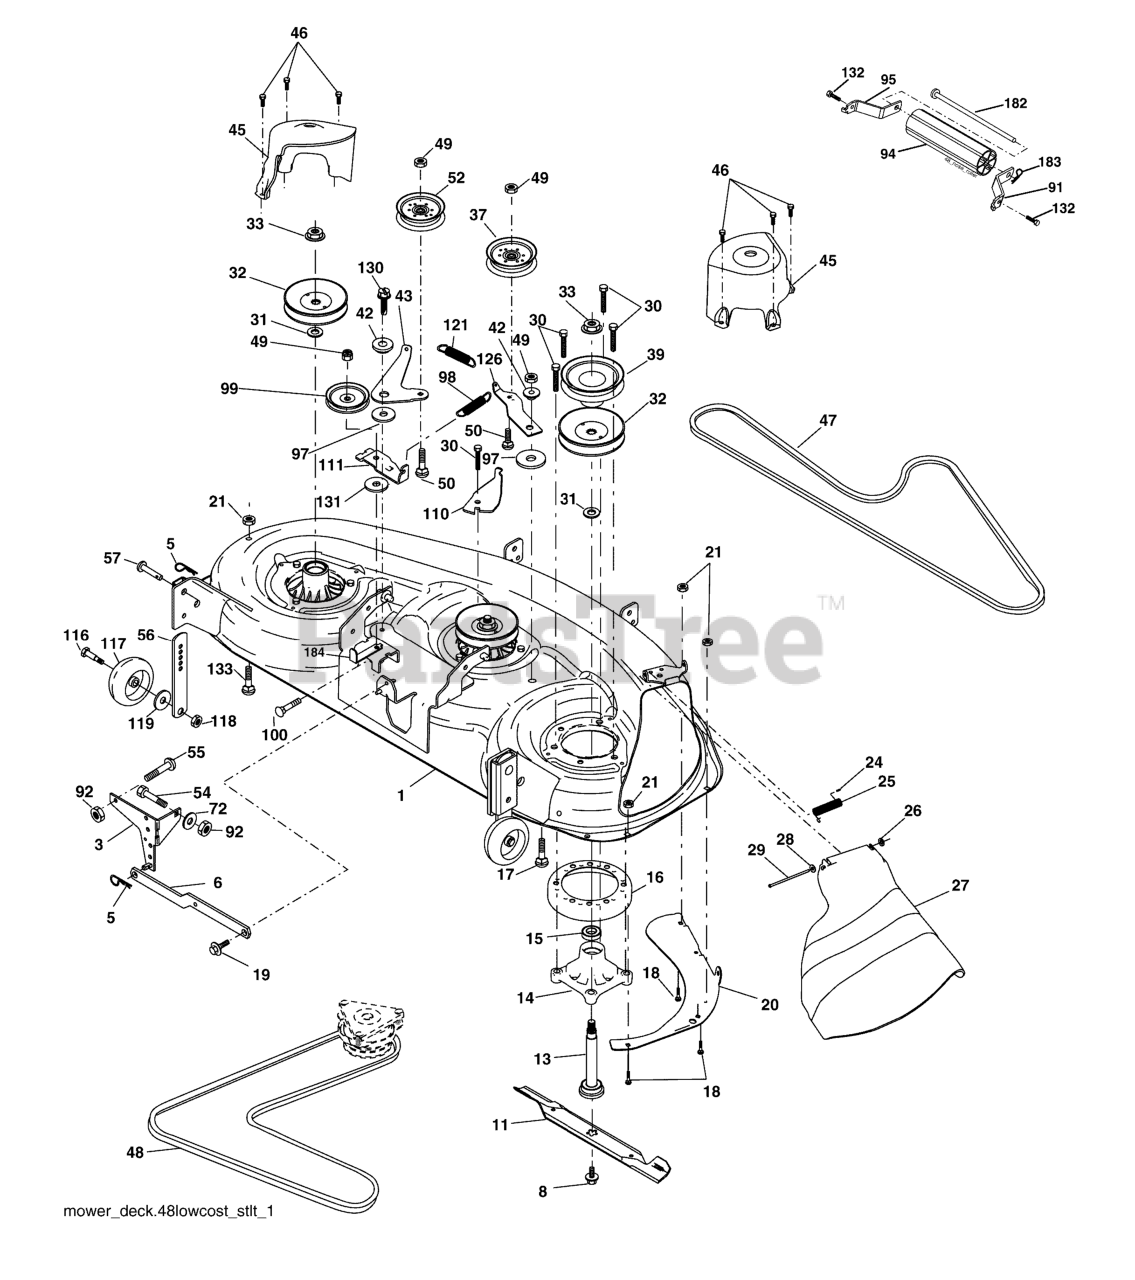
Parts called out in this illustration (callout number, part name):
1	DECK WELDMENT
3	BRKT ASM SWAY BAR
5	RETAINER-SPRNG RB
6	BAR SWAY DECK
8	BOLT 7/16 ASM BLADE
11	48" HI-LIFT BLADE
13	SHAFT ASM W/LOWER BEARING
14	HOUSING, MANDREL 48"
16	STRIPPER.MANDREL.ROUND.BLACK
17	BOLT
18	BOLT
19	BOLT SHD 5/16-18
20	BAFFLE, VORTEX MWR
21	LOCKNUT
24	CAP-SLEEVE LT
25	SPRING, TORSION
26	NUT PUSH M
27	DEFLECTOR SUBS TO 532 180655
28	Washer 11/32 x 5/8 x 16 Ga.
29	ROD.HINGE
30	SCREW, WASHER HEAD
31	WASHER.SPACER.MANDREL
32	PULLEY MANDREL
33	NUT, FLG TOPLOCK 9/16"
37	PULLEY.IDLER.FLAT
39	PULLEY.DRIVEN.DECK.48'
42	SPACER RETAINER
43	ARM, IDLER SECONDARY
45	COVER.MANDREL.DECK.48"
46	SCREW.1/4-20X5/8
47	V-BELT, 48"SECONDARY
48	V-BELT PRIMARY 48"
49	NUT LOCK FLG 3/8-16 UNC
50	BOLT.3/8-16X1.50
52	PULLEY.IDLER.FLAT.46.PR.DR.
54	BOLT
55	BOLT D
56	BAR.ADJUST.WHEEL.ANTI.SCALP.BL
57	RIVET.PIN.HEAD.YELLOW.
72	WASHER
91	BRKT.NOSEROLLER.RH.48"
92	NUT
94	NOSE ROLLER 48"
95	BRKT.NOSEROLLER.LH.48"
98	SPRING PRIMARY DRIVE
99	RP PULLEY.V.IDLER.
100	BOLT
110	ARM, SPRING SECONDARY
111	ARM SPRING FIXED TENSION
116	SHOULDER BOLT
117	RP WHEEL. GUAGE RALLY
118	LOCKNUT
119	WASHER.5/16.FLAT.STE.STD.
121	SPRING.DRIVE.SECONDARY.48".DEC
126	ARM, IDLER PRIMARY DECK
130	SCREW 3/8-16X1
131	Washer 13/32 x 1 x 6 Ga.
132	SCREW, 3/8-16X3/4
133	BOLT.CARR.SQNK.5/16-18UNC.X3/4
182	ROD.ROLLER.NOSE.NARROW.48"
183	SPRING RETAINER
184	KEEPER BELT IDLER PLATED
